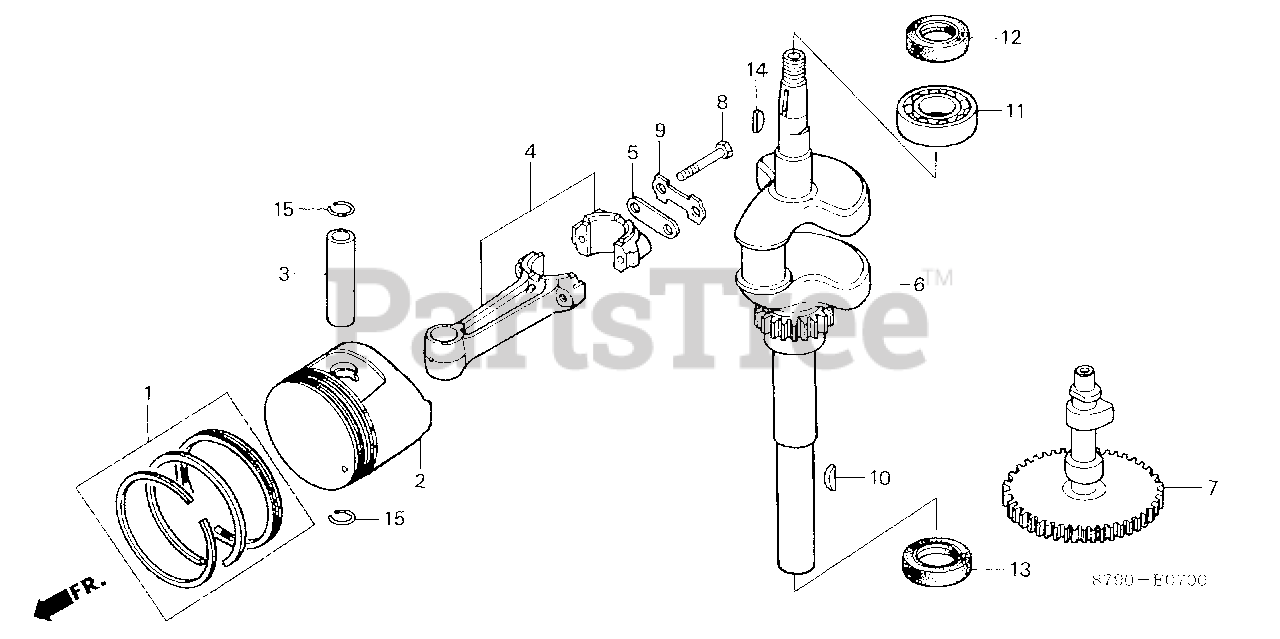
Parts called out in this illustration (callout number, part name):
1	RING SET, PISTON (STD)
1	RING SET, PISTON (0.25)
1	RING SET, PISTON (0.50)
1	RING SET, PISTON (0.75)
2	PISTON (STD)
2	PISTON (0.25)
2	PISTON (0.50)
2	PISTON (0.75)
3	PIN, PISTON
4	ROD, CONNECTING
5	WASHER A, CONNECTING ROD
6	CRANKSHAFT
8	BOLT, HEX. (6X37)
9	WASHER, TONGUED
10	KEY, P.T.O. SHAFT
11	BEARING, RADIAL BALL (62/22)
12	OIL SEAL (22X35X6)
13	OIL SEAL (25X38X7)
13	OIL SEAL (25X38X7) (ARAI)
14	KEY, WOODRUFF (25X14)
15	CLIP, PISTON PIN (15MM)
